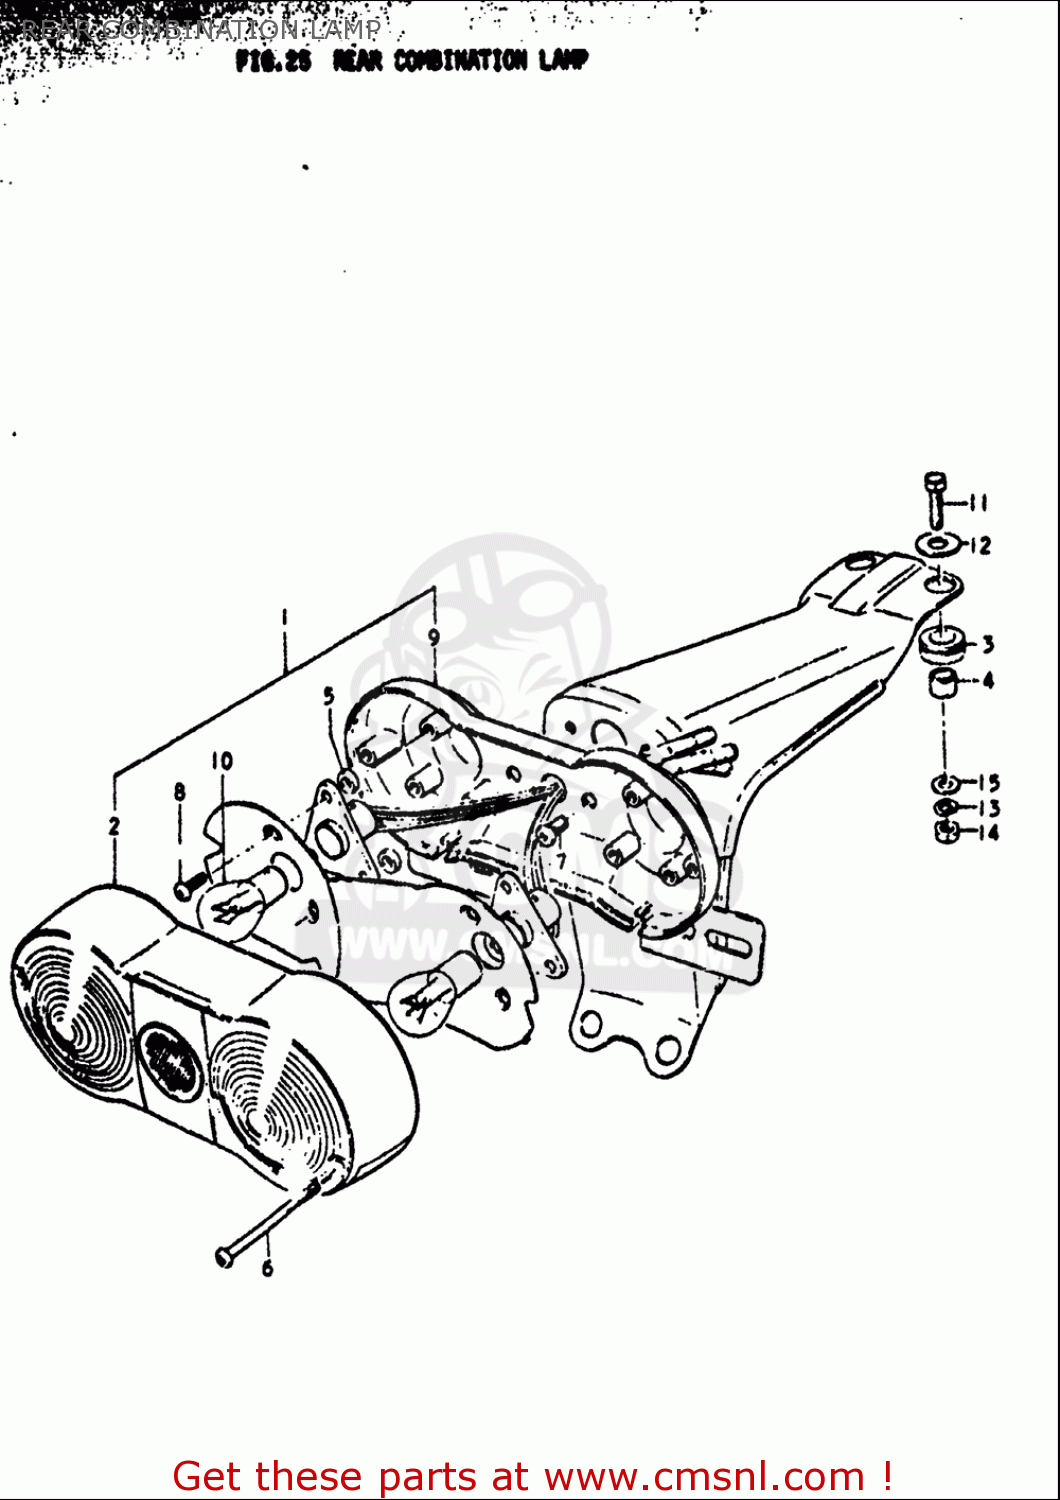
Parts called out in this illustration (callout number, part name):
2	LENS,REAR COMBINATION LAMP
3	CUSHION
4	SPACER
6	SCREW
7	SCREW
8	SCREW
10	BULB(12V23W)
11	BOLT 6X23
12	WASHER(6.5X20X1.6)
13	WASHER,LOCK
14	NUT
15	WASHER
